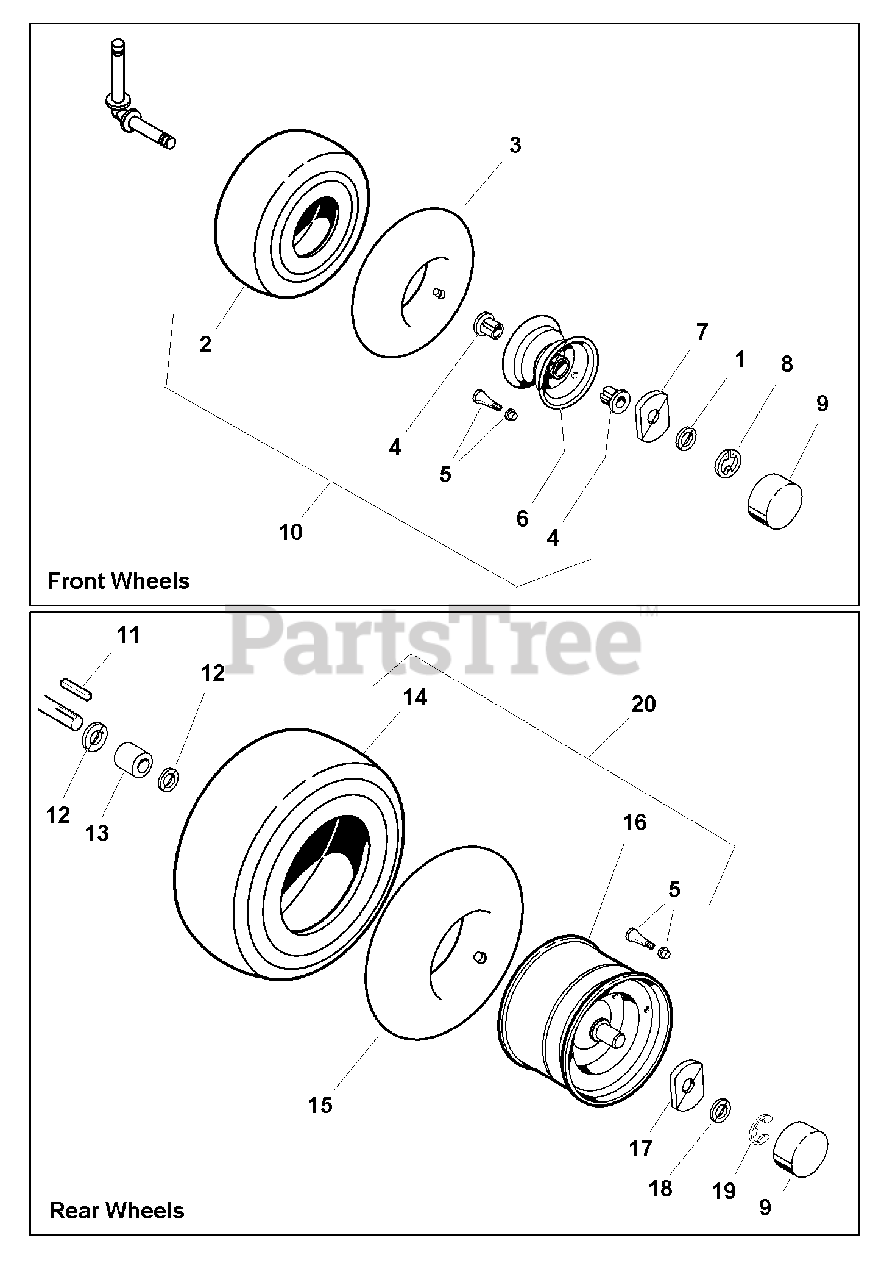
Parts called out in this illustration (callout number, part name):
1	WASHER
2	TIRE, 15 X 6.00 - 6, Super Turf
3	TUBE, 4.10/3.50 - 6
4	BEARING, Ball
5	VALVE STEM & CAP ASSEMBLY
6	WHEEL, 4.50 X 6.00, (Includes Ref. No. 4)
7	WASHER, Special
8	RING, Retaining
9	CAP, Hub
10	WHEEL & TIRE ASSEMBLY, (Includes Ref. Nos. 2, 4, 5 & 6)
11	KEY
12	WASHER
13	SPACER
14	TIRE, 20 X 10.00 -8, Super Turf
15	TUBE, 20 X 8.00 - 10
16	WHEEL, 7.00 x 7.96
17	WASHER, Special
18	WASHER
19	RING, E Retaining
20	WHEEL & TIRE ASSEMBLY, (Includes Ref. Nos. 5, 14 & 16)
